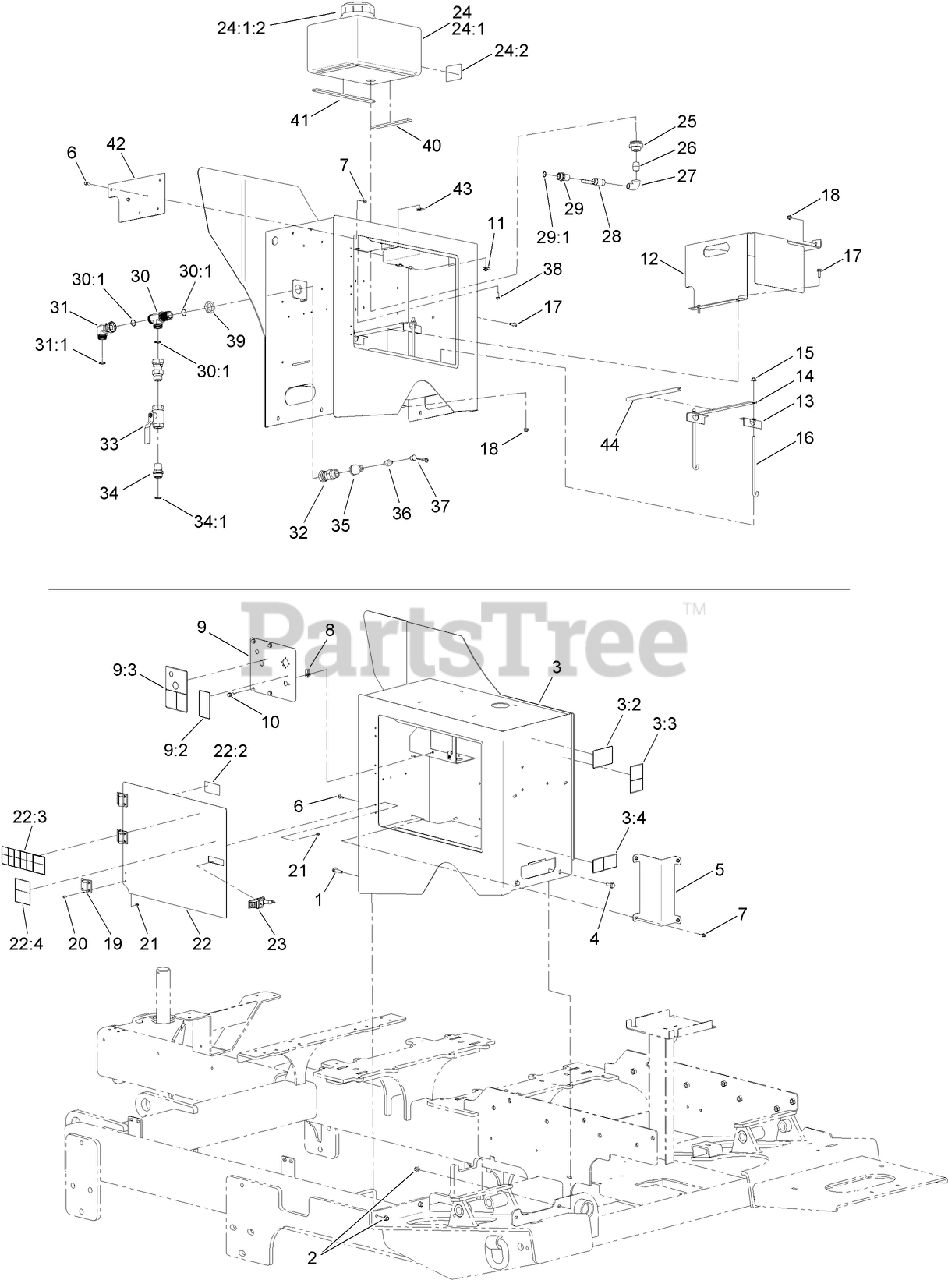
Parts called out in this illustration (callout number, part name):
1	SCREW-HHF
2	NUT-LOCK, NI
3	CONTROL BOX ASM
3:2	DECAL-RAISE AND LOWER
3:3	DECAL-DANGER, BACK UP
3:4	DECAL-WARNING, HYDRAULIC PRESSURE
4	SCREW-HHF
5	PLATE-CORNER, CONSOLE
6	SCREW-HHF
7	NUT-FLANGE, NI
9	CONTROL PLATE ASM
9:2	DECAL-DISCONNECT, BATTERY
9:3	DECAL-REAR CONTROLS OVERLAY
10	SCREW-HHF
12	PLATE-COVER
13	ANGLE-HOLDDOWN, BATTERY
14	PLATE-Battery Hold Down
15	NUT-HF, NI
16	BOLT-HOLDDOWN, BATTERY
17	SCREW-HHF
18	NUT-LOCK, HHF
21	NUT-HF
22	DOOR ASM
22:2	DECAL-WARNING, BATTERY
22:3	DECAL-SAFETY
22:4	DECAL-DANGER, NO RIDERS (REAR)
23	LATCH-TRIGGER, RAISED (W/LOCK)
24	ANTIFREEZE TANK ASM
24:1	TANK
24:1:2	LID-TANK
24:2	DECAL-ANTIFREEZE
25	FITTING-TANK, BULKHEAD (PLASTIC)
26	NIPPLE-STRAIGHT
27	ELBOW-STREET, 90 DEG
28	VALVE-BALL
29	FITTING-STRAIGHT
29:1	O-RING
30	FITTING-TEE, BULKHEAD
30:1	O-RING
31	FITTING-SWIVEL, 90 DEG
31:1	O-RING
32	FITTING-STRAIGHT
33	VALVE-BALL
34	FITTING-STRAIGHT
34:1	O-RING
35	FITTING-REDUCER
36	NIPPLE-CONNECT, QUICK
37	CAP-DUST
38	SCREW-HHF
39	NUT-BULKHEAD
40	STRIP-SEAL
41	STRIP-SEAL
42	PLATE-LOCKOUT, CYLINDER
44	TRIM-BATTERY
